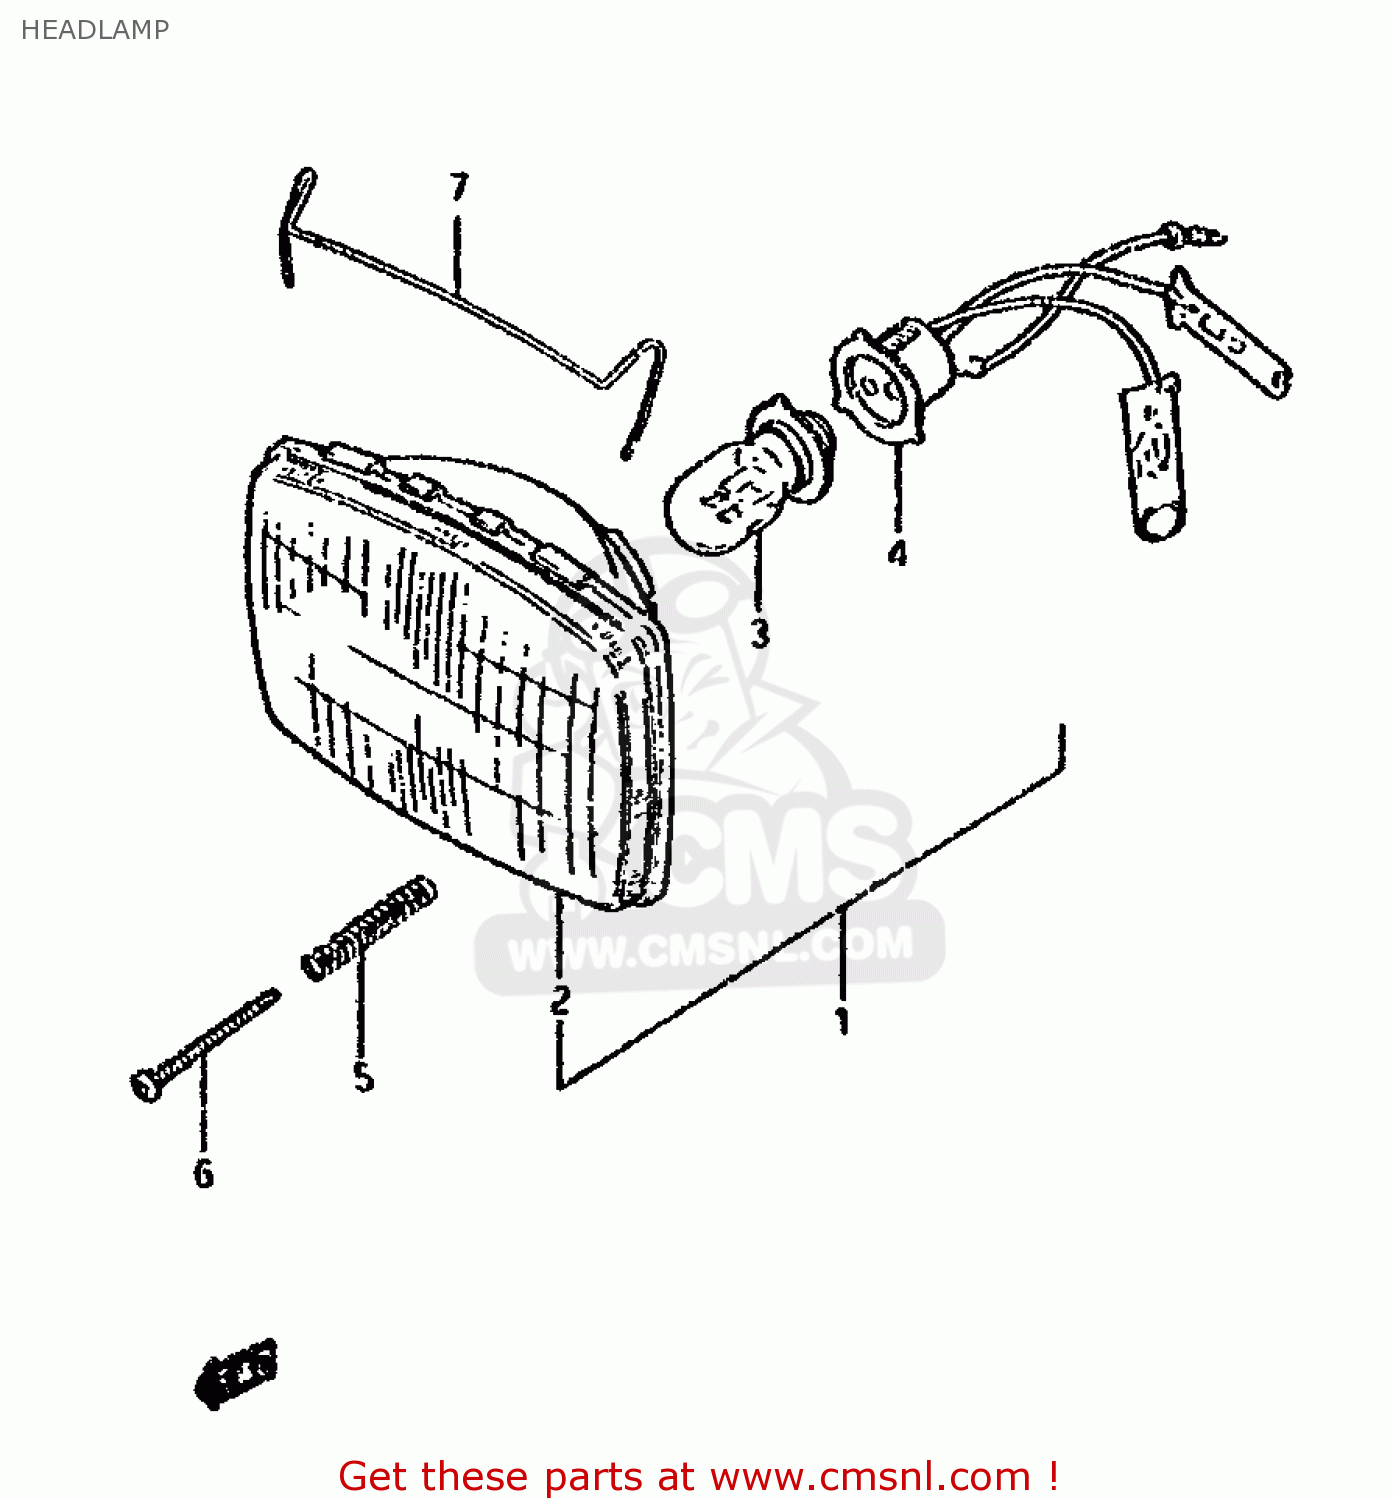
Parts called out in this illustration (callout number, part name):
1	HEADLAMP ASSEMBLY
2	LAMP UNIT
3	BULB(6V15/15W/STANLEY,A3598HA)
4	SOCKET,HEADLAMP
5	SPRING,HEAD LAMP ADJUSTER
6	SCREW
7	SPRING,SUPPORT
